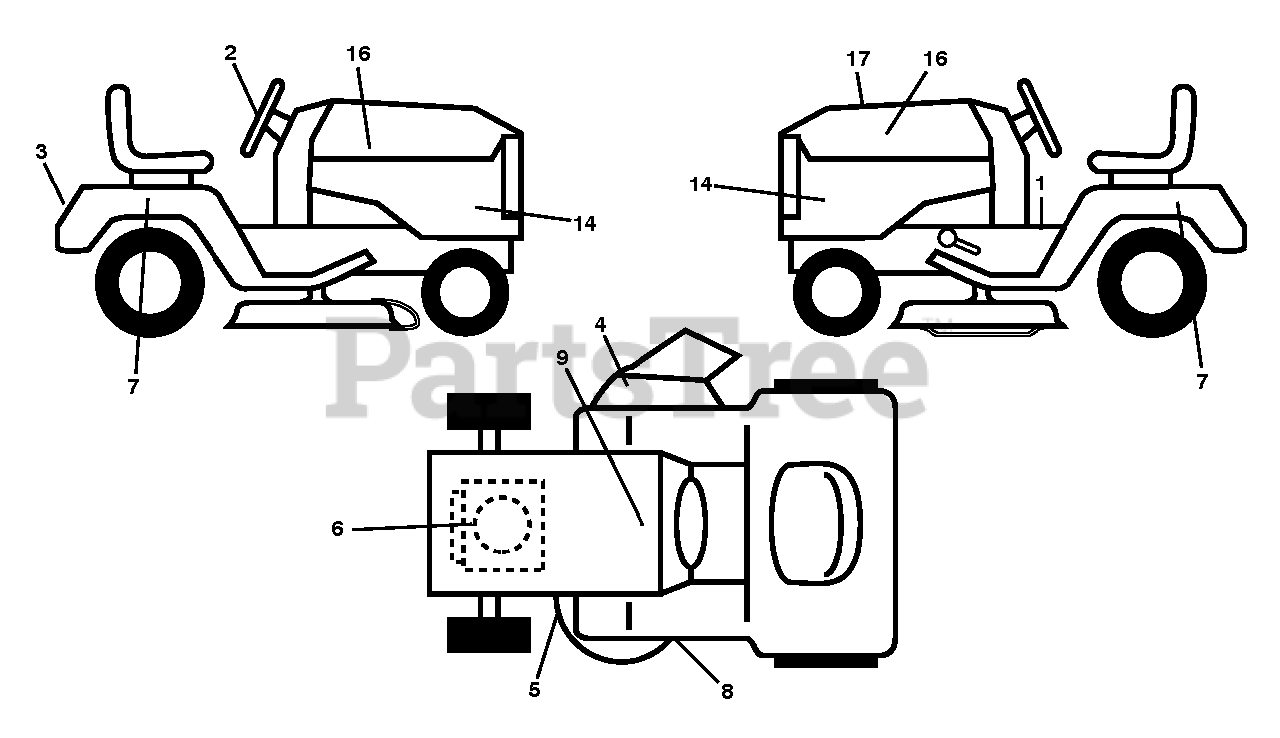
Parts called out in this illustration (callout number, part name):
1	Fender Warning Decal, English
2	DECAL.STEER.WHEEL.POULAN.PRO
4	DECAL.WARN.KEEP.HAND.AWAY
5	DECAL.MOWER
6	DECAL.ENG.BS.23HP.XRD.TWIN
8	DECAL.MOWER.SCH.48/54
9	DECAL BTRY SYMBOLS
